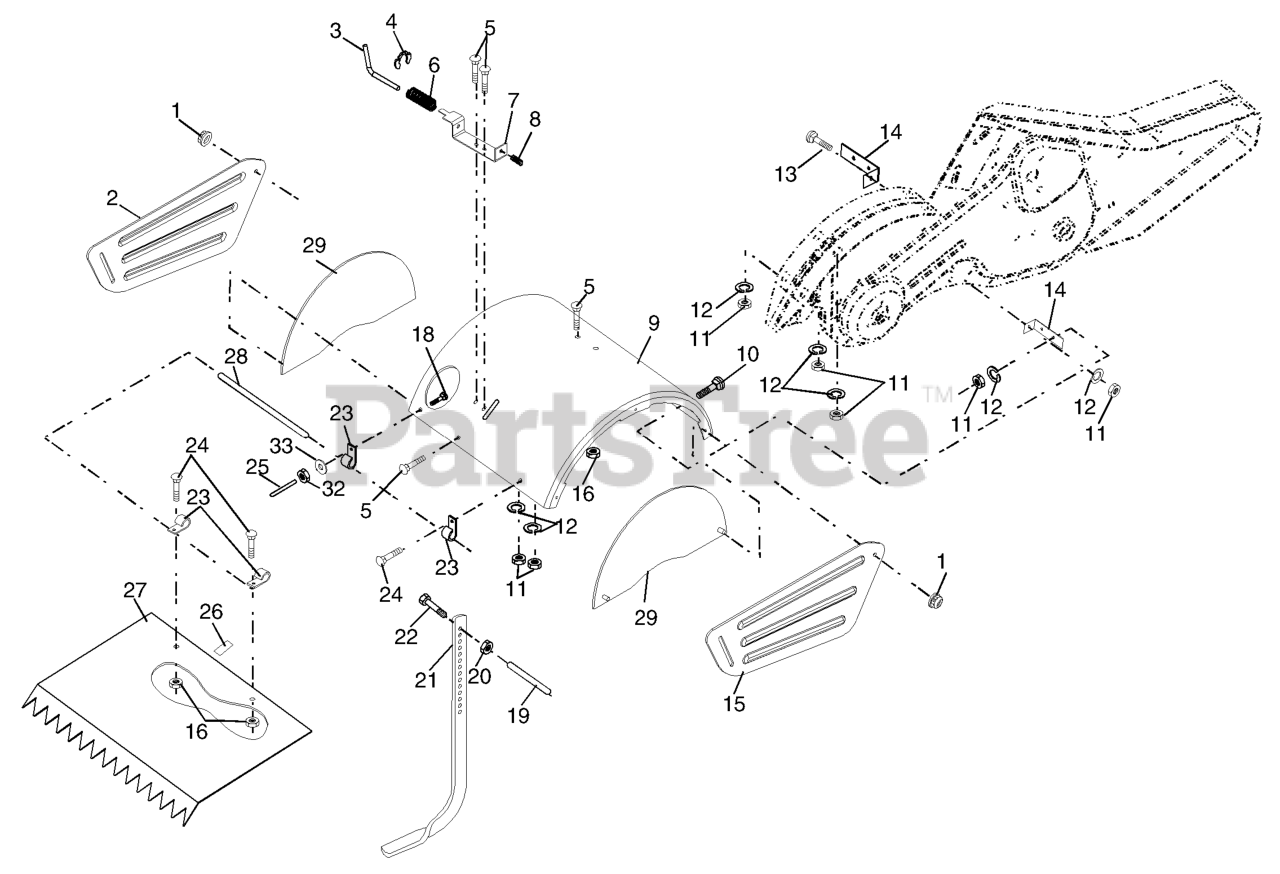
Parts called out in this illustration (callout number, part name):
1	NUT LOCK HEX FLANGE 5/16-18
2	SHIELD
3	STAKE PIN TI
4	RING, KLIP
5	BOLT, RDHD SQNK 5/16-18 X 3/4
7	BRACKET.LATCH.STAKE.3.20.BLACK
8	SPRING CRT
9	SHIELD
10	BOLT
11	NUT
12	WASHER.LOCK.HVY.HLCL.SPR.5/16
13	BOLT.CARRIAGE.5/16-18
14	BRACKET.TINE.SHIELD.TILLER.BLA
15	SIDE SHIELD RH
16	NUT T
20	NUT.HEX.3/8-16UNC
21	STAKE.DEPTH.16.CRT.BLACK
22	BOLT.375-16
24	BOLT
25	VINYL CAP TI
26	PAD IDLER TI
27	SHIELD LEVELING
28	PIN.HINGE.TILLER
29	SIDE SHIELD
32	NUT
33	LOCKWASHER
